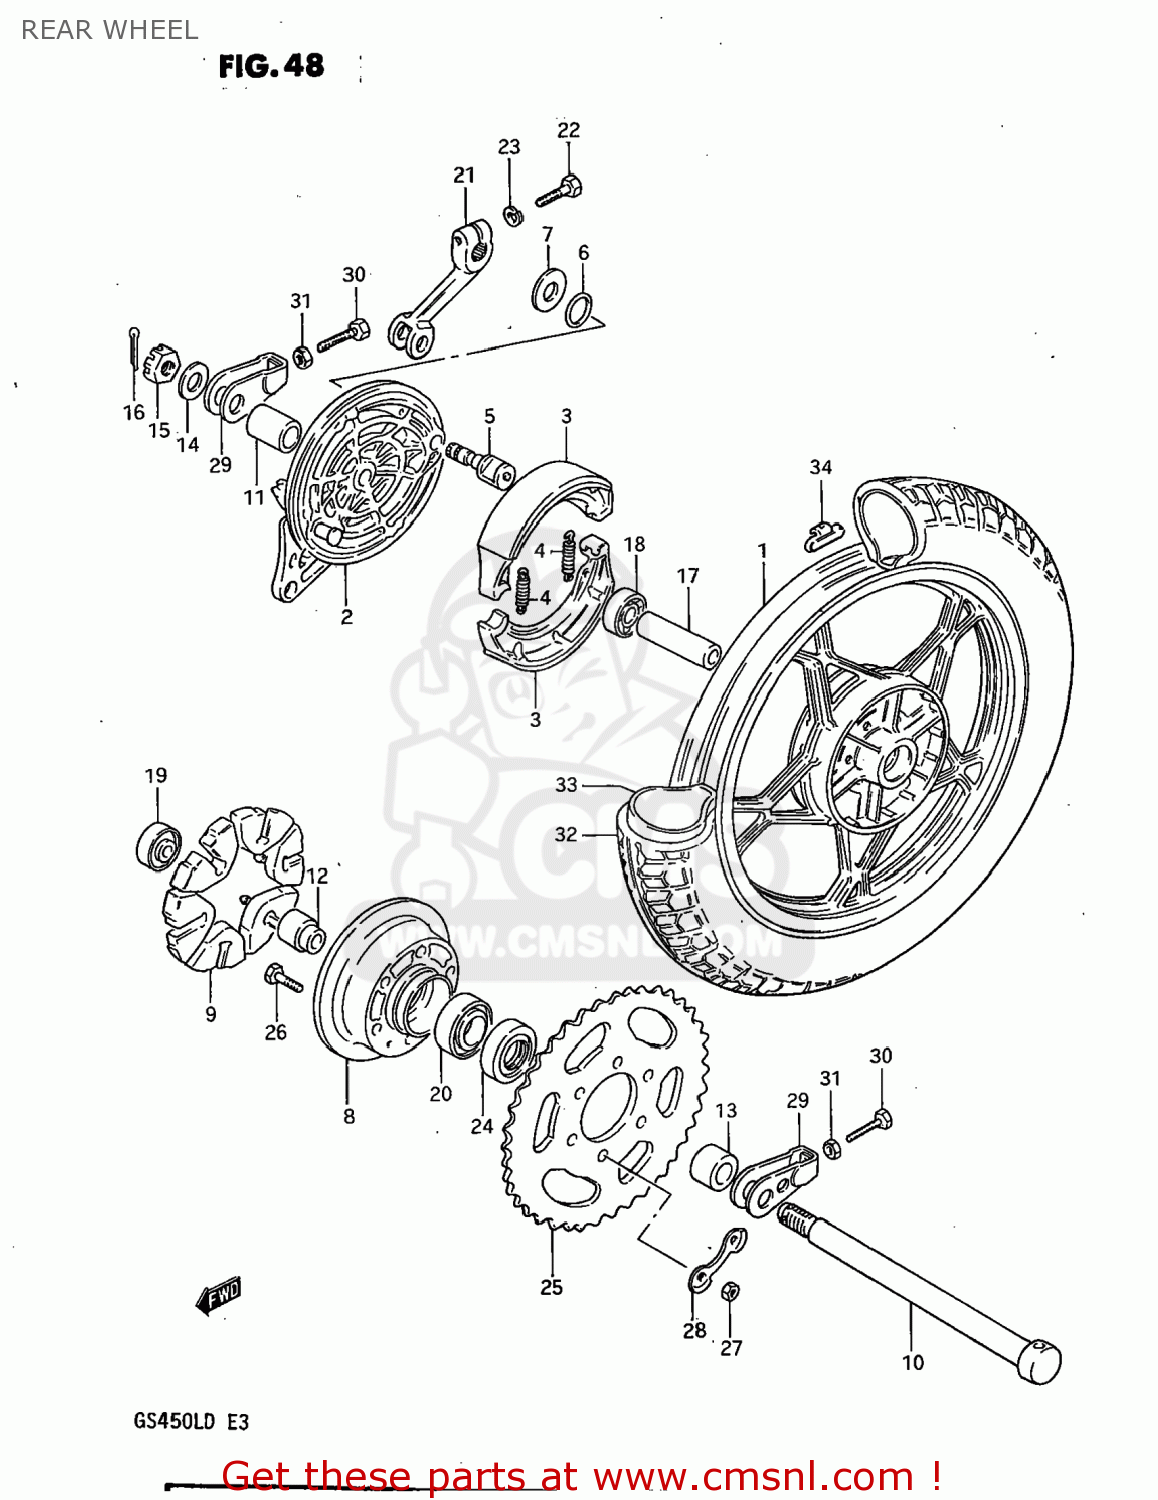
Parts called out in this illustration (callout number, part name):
1	CASTING WHEEL,REAR 2.15
2	PANEL,REAR HUB
3	SHOE,BRAKE
4	SPRING,BRAKE SHOE
5	CAM,FRONT BRAKE
6	O-RING,BOSS
7	WASHER (15X24X1.6)
8	DRUM,REAR SPROCKET MOUNT
9	ABSORBER,RR HUB SHOCK
10	AXLE,REAR
11	SPACER(17.5X28X44.8)
12	SPACER,REAR HUB BEARING
13	SPACER(17X30.5X22.3)
14	WASHER (17X30X3.2)
15	NUT
16	PIN,COTTER
17	SPACER (17.6X24X57)
18	BEARING
19	BEARING
20	BEARING
21	LEVER,REAR BRAKE CAM
22	BOLT
23	LOCK WASHER
24	SEAL,OIL(30.5X52X8)
25	SPROCKET,RR
26	BOLT
27	NUT
28	WASHER
29	ADJUSTER,CHAIN
30	BOLT 8X50
31	NUT
32	TIRE
33	TUBE ASSEMBLY,WHEEL,INNER
34	BALANCER,WHEEL
